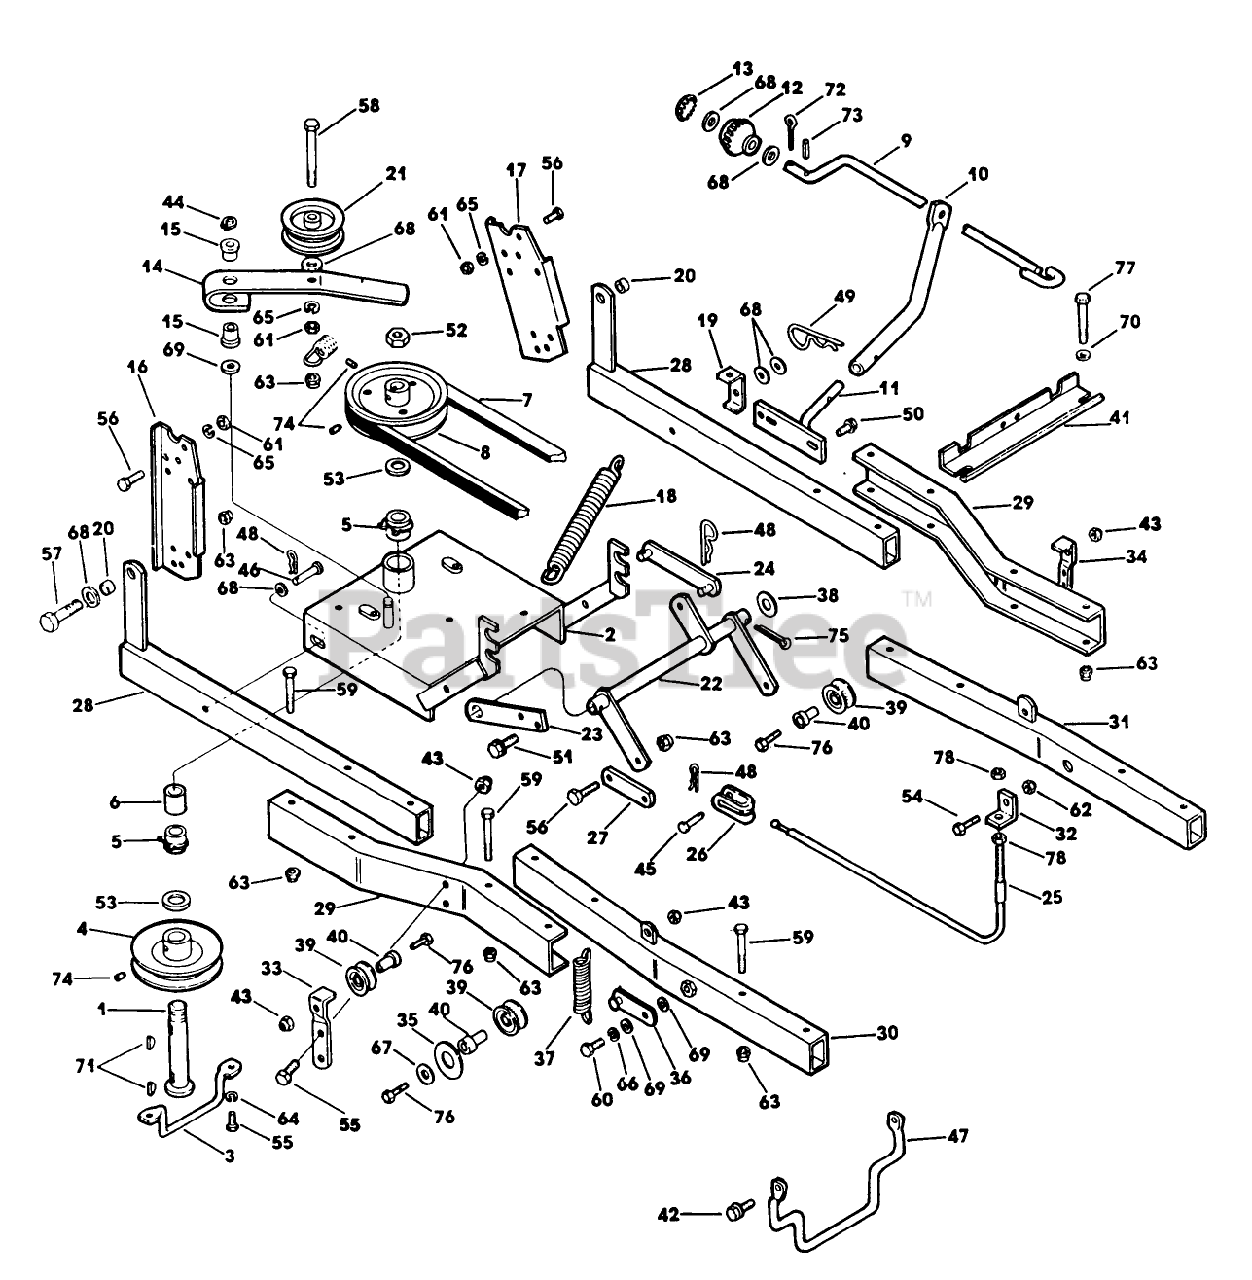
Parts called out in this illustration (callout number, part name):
1	SHAFT AY *NP
2	SUPPORT ASSY PULLY
7	V-Belt (Primary)
10	TUBE-CRANK
15	BUSHING
17	BRACKET MOUNTING
24	LIFT LINK
28	REAR FRAME AY
30	FRONT FRAME AY RH
42	SCREW-THREAD FRMG
44	SNAP RING
48	PIN - SPRING CLIP
53	WASHER-SHIM
55	SCREW - HEX
62	NUT-LOCK, CONE
63	NUT-LOCKING
74	SET SCREW
